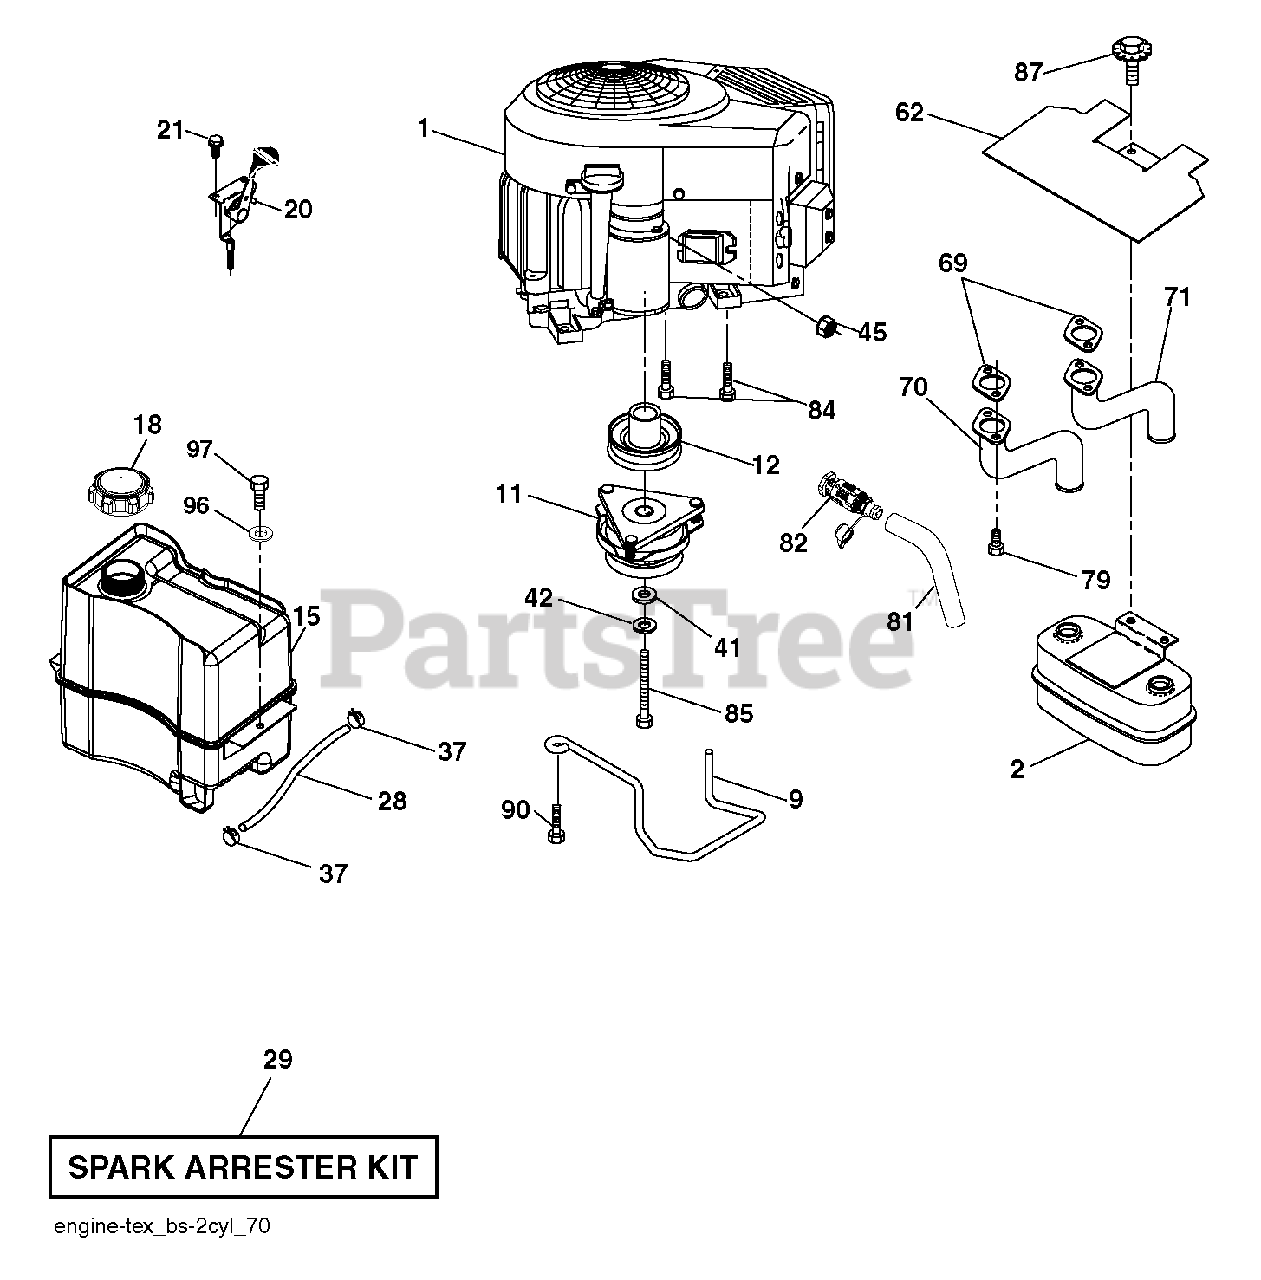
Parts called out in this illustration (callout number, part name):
2	MUFFLER.TWIN.CYL.LOW.TONE
9	KEEPER.BELT.ENGINE.4.2
11	CLUTCH.ELECTRIC.LT.48"*
12	PULLEY.ENGINE.TUFFTORQ
15	TANK FUEL FRT 1.5 GAL
18	CAP ASM.FUEL.2.25"FR.
20	CONTROL.TH/CK.COBRA.B&S.TWN.
21	SCREW.#10 X 0.750.BOS THREAD
29	ARRESTER SPARK (OPTIONAL)
42	LOCKWASHER
45	NUT
62	SHIELD.HEAT.MUFFLER
69	GASKET.MUFFLER
70	EXHAUST TUBE LH *SUBS/2*
71	EXHAUST TUBE RH
79	SCREW.SOCKET.HEAD.5/16-18
81	TUBE, DRAIN OIL ASM.
82	VALUE.OIL.DRAIN
85	BOLT HEX 7/16-20X4-1/4"
87	BOLT, 5/16-18 X 1 3/4
90	SCREW 3/8-16X1
97	SCREW HEXWSHR 1/4-20X3/4
